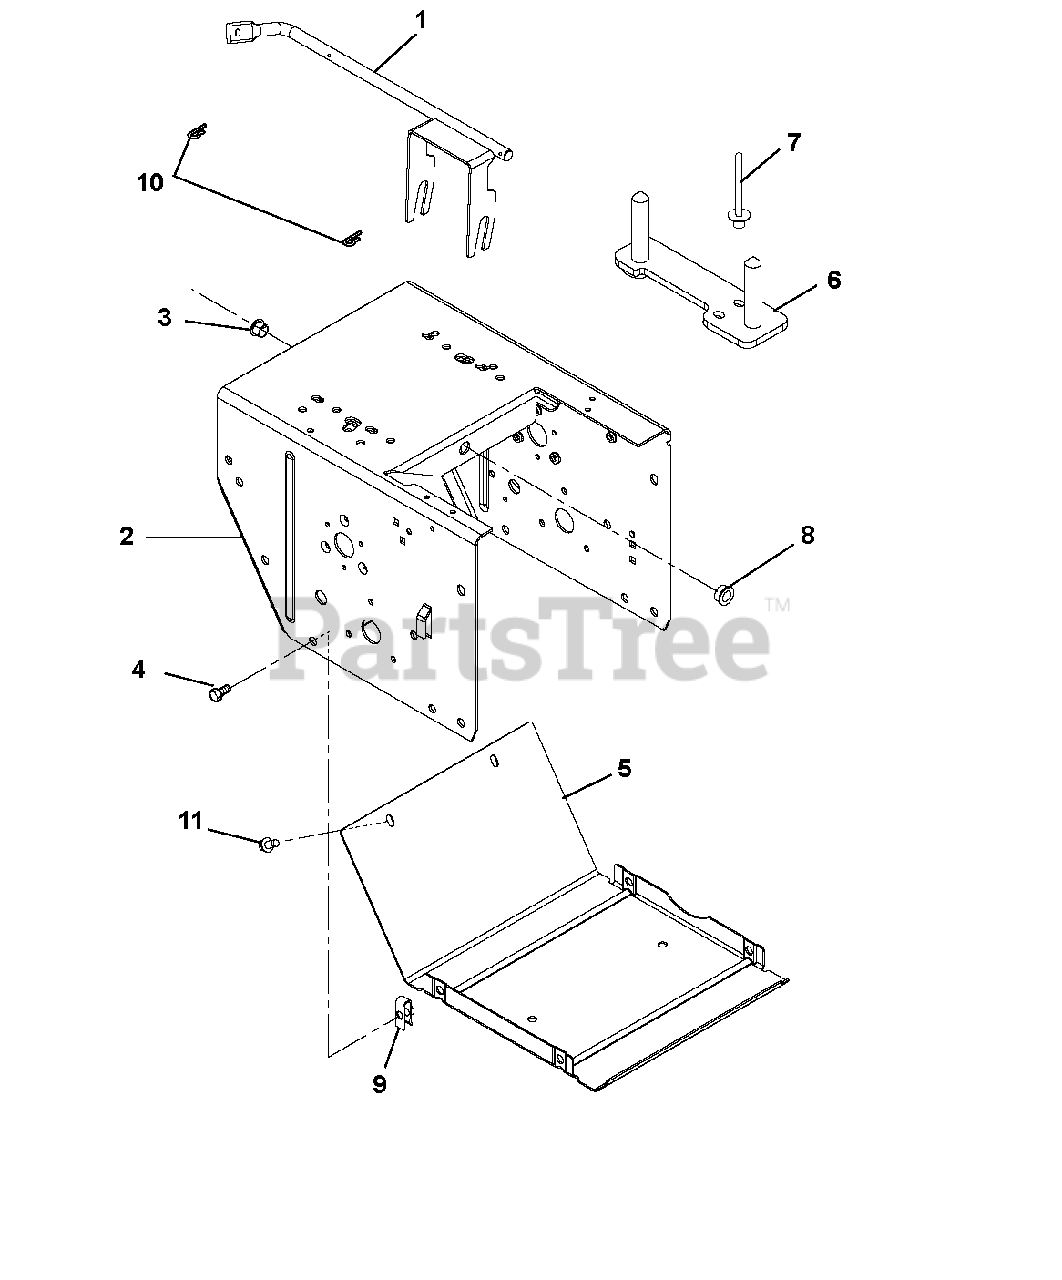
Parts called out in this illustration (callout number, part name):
1	ARM, SHIFT-WELDMENT
2	PRO FRAME, MAIN
3	BUSHING, POLYLINER-.50 SPLIT
4	BLT-HEX .25-20X.75 HWH YZ GR5
5	COVER, BOTTOM
6	STRAP, ENGINE BOLT-LARGE BRIGG
7	RVT-POP .187 YZ
8	BUSHING, POLYLINER-.50 SNAPIN
9	NUT-RTNR .25-20X.56
11	SCR-TAP .25-20X.50 HWH TR YWZ
